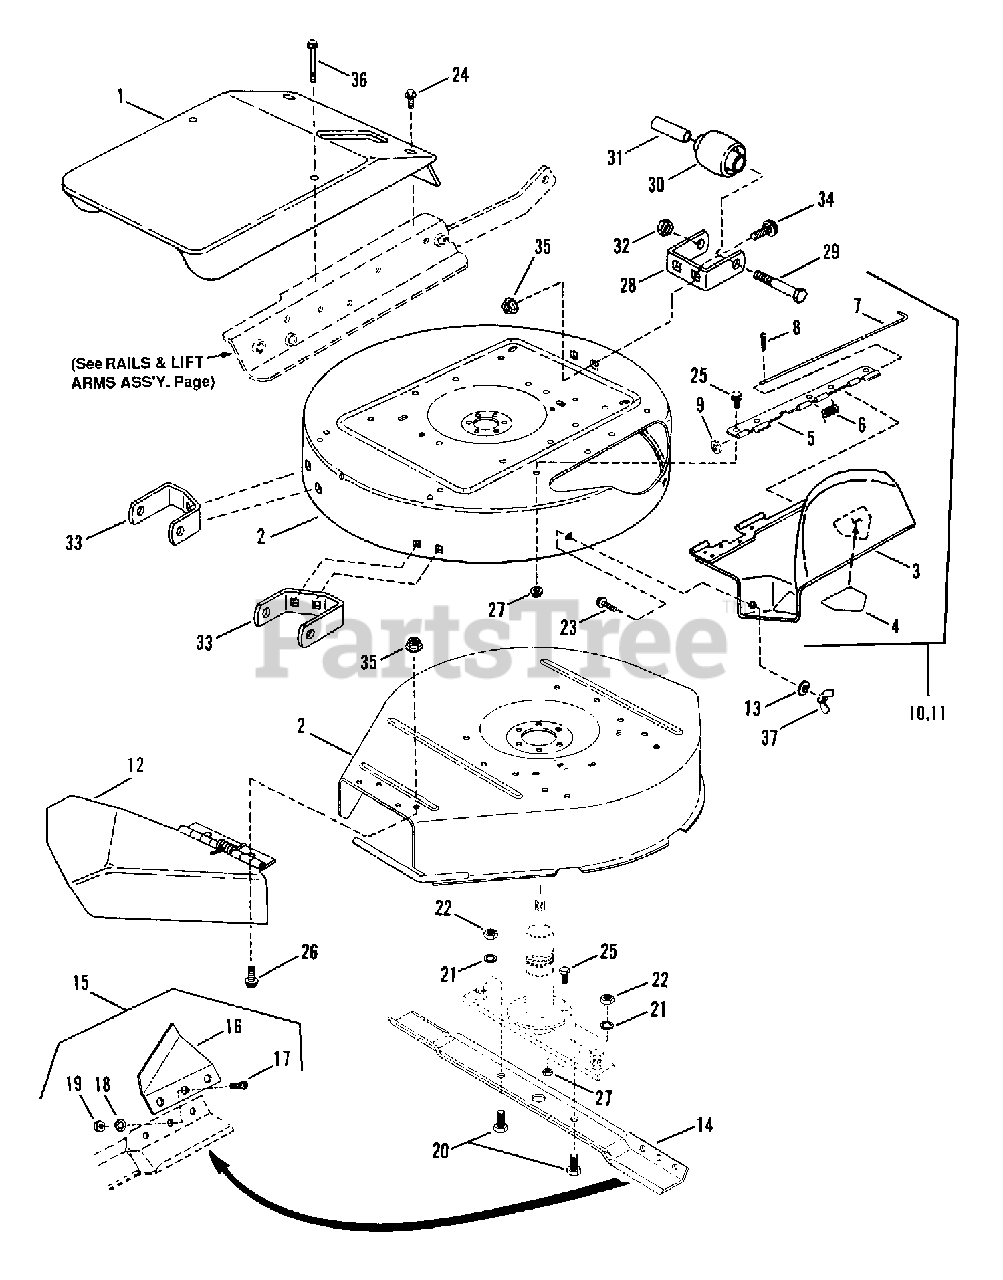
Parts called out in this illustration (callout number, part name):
1	COVER, Spindle
2	25" DECK (Includes decals)
2	28" DECK (Includes decals)
2	30" DECK (Includes decals & deflector)
2	33" DECK (Includes decals)
3	DEFLECTOR, Discharge (25" Deck)
3	DEFLECTOR, Discharge (28" & 33" Deck)
4	DECAL, Danger (Cut Finger)
5	HINGE, Deflector
6	SPRING, Hinge
7	PIN, Hinge
8	PIN, 3/32 x 3/4" Cotter
9	WASHER, 1/4 Flat
10	DEFLECTOR ASSY., Discharge (25" Deck)
11	DEFLECTOR ASSY., Discharge (28" & 33" Deck)
12	DEFLECTOR, Discharge (30" Decks)
13	WASHER, 5/16 Flat
14	25" BLADE
14	28" BLADE
14	30" BLADE
14	33" BLADE
15	AIR LIFT KIT, Hi-Vac
16	AIR LIFT, Hi-Vac (3 hole)
17	SCREW, 5/16-24 x 11/16" Machine
18	WASHER, 5/16-24 Internal Tooth Lock
19	NUT, 5/16-24 Hex
20	SCREW, 1/2-20 x 1" Hex Head Cap
21	WASHER, 1/2 Internal Tooth Lock
22	NUT, 1/2-20 Hex Jam
23	BOLT, 5/16-18 x 3/4" Short Neck Carriage
24	SCREW, 1/4-20 x 5/8" Self-Tapping
25	BOLT, 3/8-16 x 3/4" Hex Flange Lock
26	BOLT, 5/16-18 x 1/2" Hex Flange Lock
27	NUT, 3/8-16 Hex Flange Lock
28	BRACKET, Gage Wheel (Front)
29	SCREW, 3/8-24 x 3-3/4" Hex Head Cap
30	WHEEL, Gage
31	SPACER
32	NUT, 3/8-24 Hex Lock
33	BRACKET, Gage Wheel (Rear)
34	BOLT, 5/16-18 x 1/2" Short Neck Carriage
35	NUT, 5/16-18 Hex Flange Lock
36	SCREW, 1/4-20 x 3-1/2" Self-Tapping
37	NUT, 5/16-18 Wing
